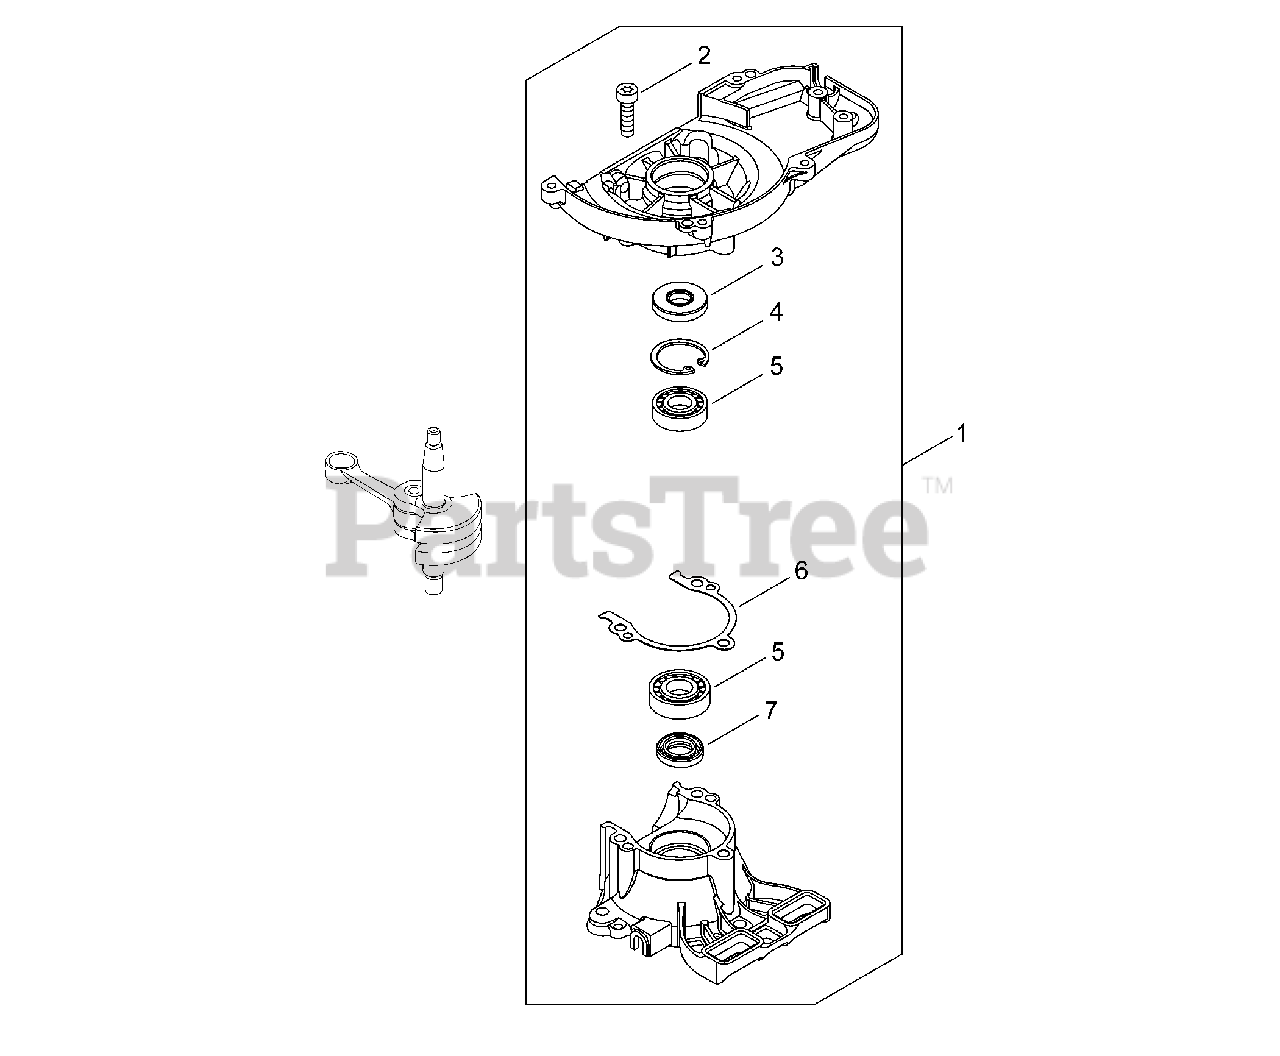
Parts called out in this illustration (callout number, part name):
1	CRANKCASE ASSY
2	BOLT, TORX 5×25
3	SEAL, OIL
4	RING, SNAP 26
5	BEARING, BALL
6	GASKET, CRANKCASE
7	SEAL, OIL
